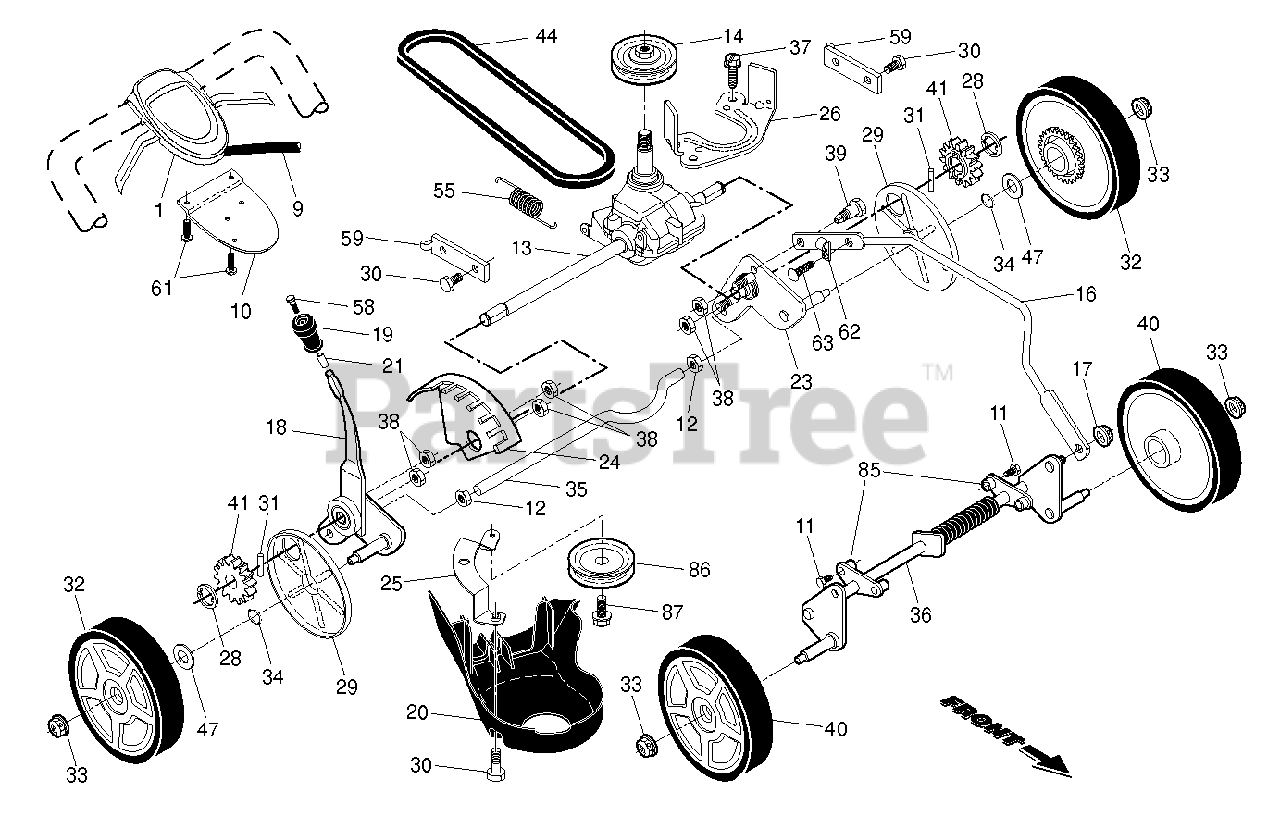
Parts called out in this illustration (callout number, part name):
1	CONTROL.EZ2.22+RG.ST.BLK/BLACK
9	CABLE.DRIVE.RWD.WALK.
10	BRACKET.DRIVE.CONTR.GEN2.BLACK
11	SCREW.HX.13X.750
12	NUT.HEX.1/2-20
13	TRANSMISSION.22+AWD.WALK.MOWER
14	PULLEY
16	ROD.CONNECTING.RGD.22+.HW.BLAC
17	NUT.LOCK.5/16-18
19	KNOB.SEL.SPRING.22+.SP.RIB.BLK
20	COVER.REAR.DRIVE.22+2013
21	SCREW.PLASTIC.ANCHOR.5/16
24	BRACKET.WHL.ADJ.9.POS.W/PAD
25	BRACKET.DRIVE.COVER.RGD.
26	BRACKET.TRANS.BELT.KEEPER.BZP
28	E-RING 7/16 RE
29	COVER.DUST.WHEEL.INNER.WALK
30	BOLT.5/16HEX.WHS.HD
31	PAWL, DRIVE
32	Wheel, 8" X 1.75 5-Spoke Rad3.Black
33	NUT.HEX.FLANGE.3/8-16.LOCKNUT
34	O-RING..070X.487.NEOPRENE
35	AXLE.REAR.RGD
36	AXLE.ASM.FRT.RGD.BZP
37	SCREW
38	NUT.HEX.FLANGE.1/4
39	SHOULDER BOLT SEMI GIMLET PT.
40	WHEEL.8X1.75.CF5SPK.RAD3.BLACK
41	PINIION.14.TOOTH.RGD
44	BELT.DRIVE.RGD.SS.WALK
47	WASHER FLUT
55	SPRING.RETURN.AUTO.
58	SCREW.12-14X1.500
59	BRACKET.SUPPORT.22+RWGD.BZP
61	SCREW, PHILLIPS HEAD 10 X 5/8
62	CLIP.CABLE.BLK
63	FASTENER.PUSH.O.250X0.783
85	BRACKET.FRT.AXLE.SUPPORT
86	PULLEY.AWD.IDLER
87	SCREW
